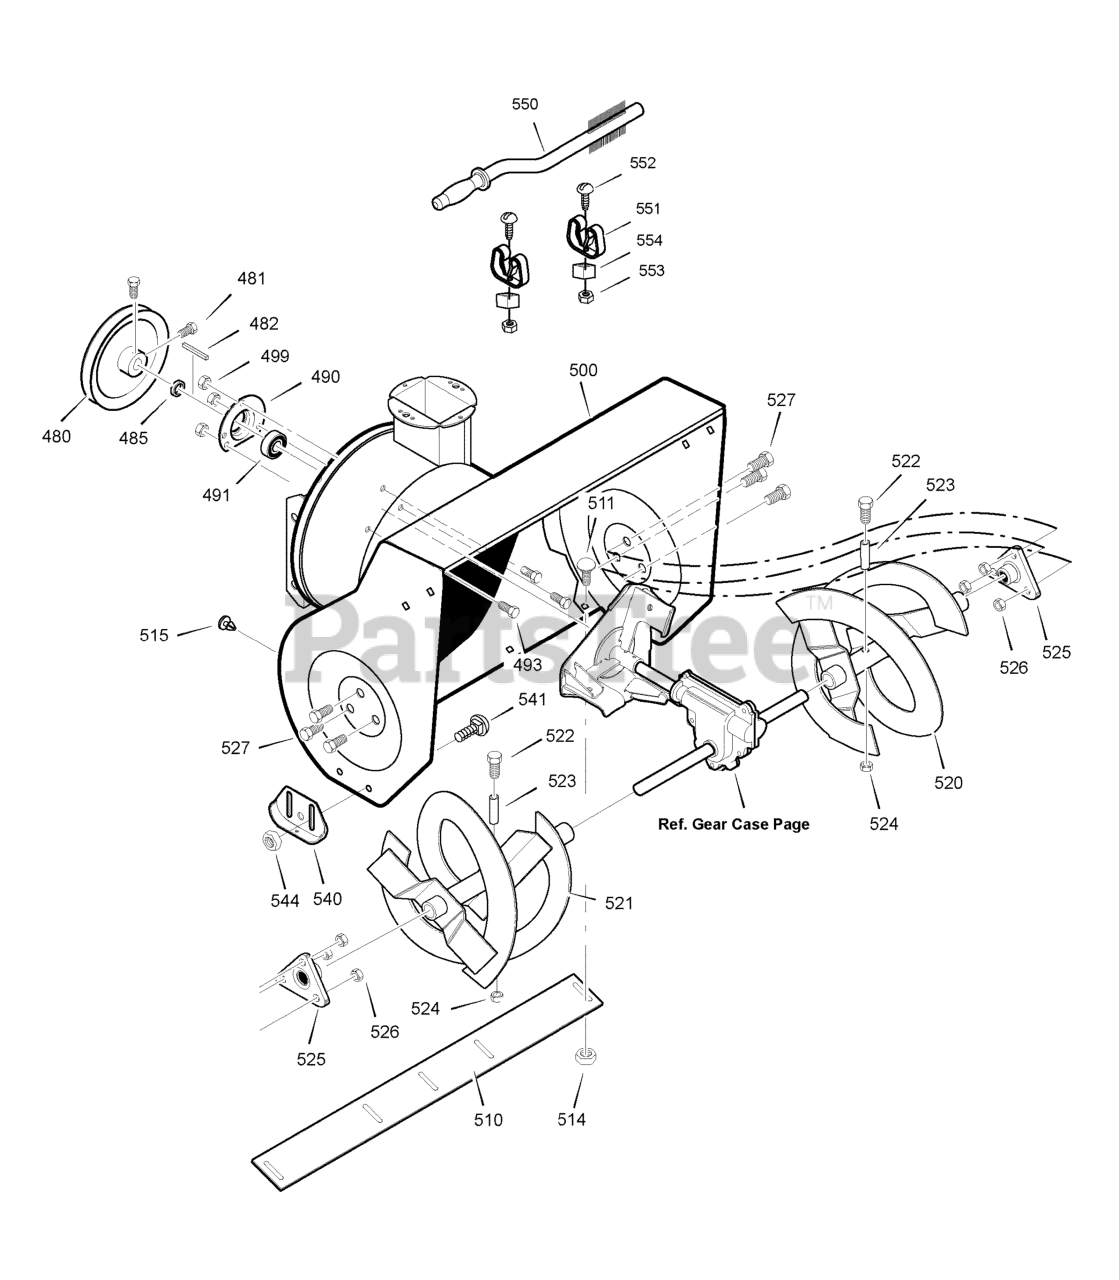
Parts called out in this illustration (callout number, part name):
480	PULLEY, 4L 6.12X .67
481	SCREW, 5/16-18 x 5/8
482	KEY, Square, 3/16 x 3/4
485	SPACER, Friction Pulley
490	RETAINER, Ball Bearing
491	BEARING, Ball
493	BOLT, HEX 5/16-18 x 1/2
499	NUT, 5/16-18
510	BLADE, Scraper
511	BOLT, 5/16-18 x 3/4
514	NUT, 5/16-18
520	AUGER ASSEMBLY, Left
521	AUGER ASSEMBLY, Right
522	SCREW, 1/4-20 x 1-3/4
523	SPACER, Sleeve
524	NUT, 1/4-20
525	BEARING, Flange
526	NUT, 5/16-18
527	SCREW, 5/16-18 x 3/4
540	SKID, Height Adjust
541	BOLT, 5/16-18 x 3/4
544	NUT, 5/16-18
550	BRUSH, Cleanout
551	CLIP, Retainer
552	SCREW
553	NUT
